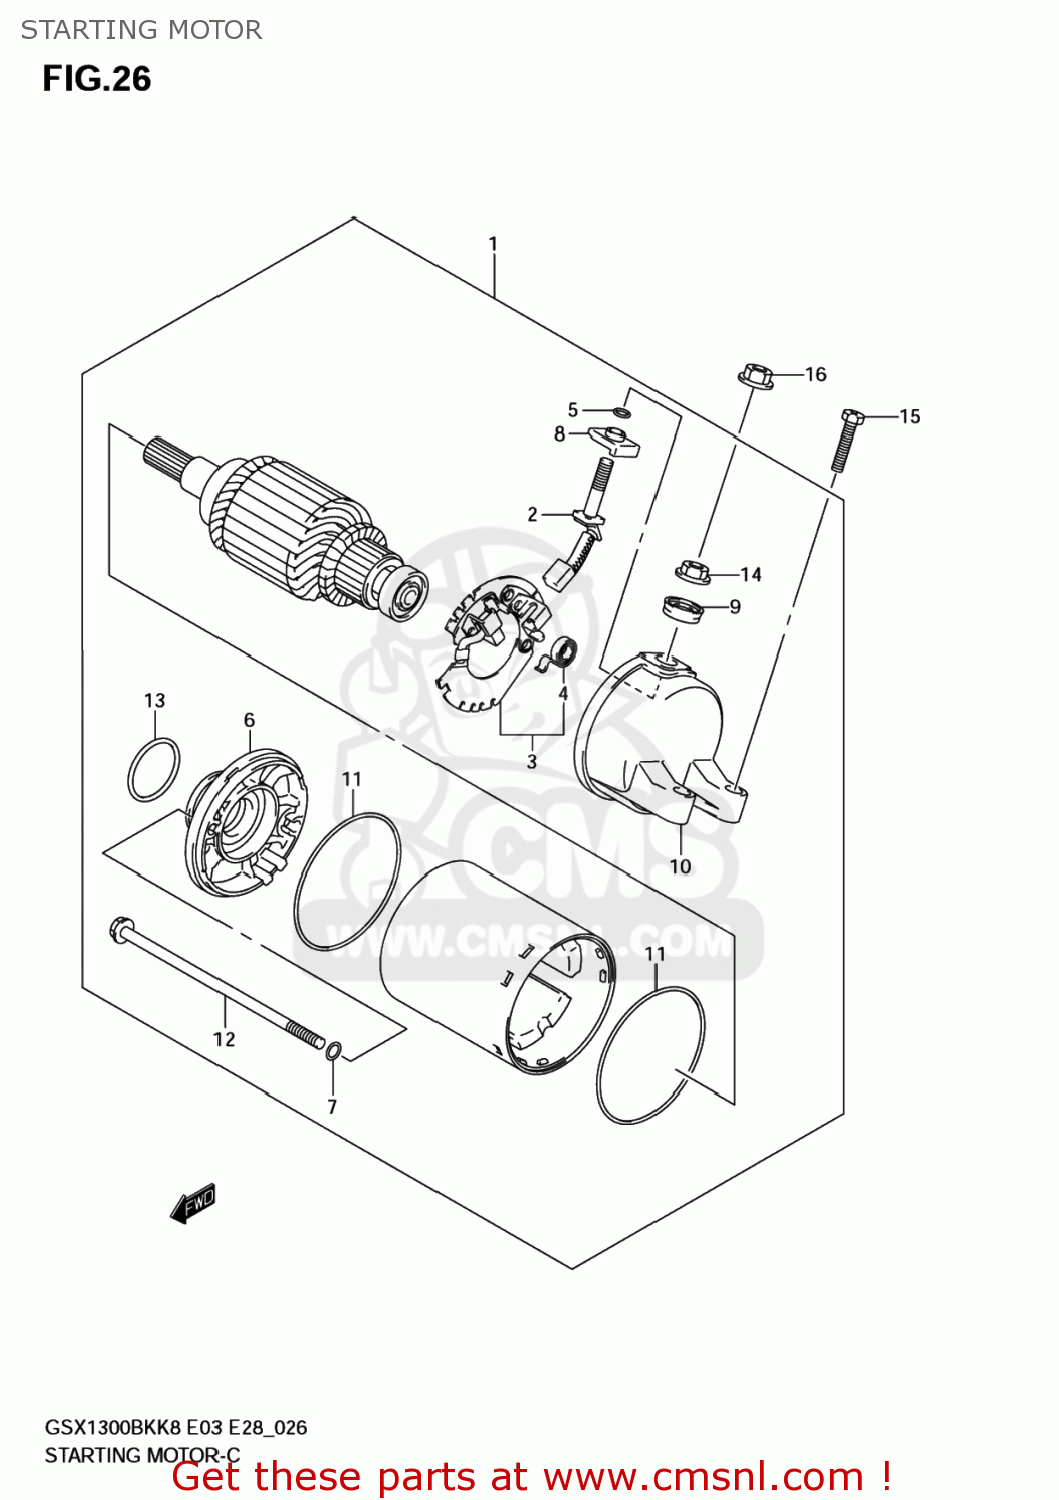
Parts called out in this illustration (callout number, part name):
1	MOTOR ASSY,STARTING
2	BRUSH SUB ASSY,STARTING MOTOR
3	HOLDER,BRUSH
4	SPRING
5	O RING
6	HOUSING ASSY,STARTING
7	O RING
8	BUSH,B
9	BUSHING
10	FRAME,STARTER END
11	O RING
12	BOLT
13	O RING(D:3,ID:24.5)
14	NUT
15	SCREW (6X25)
16	NUT
